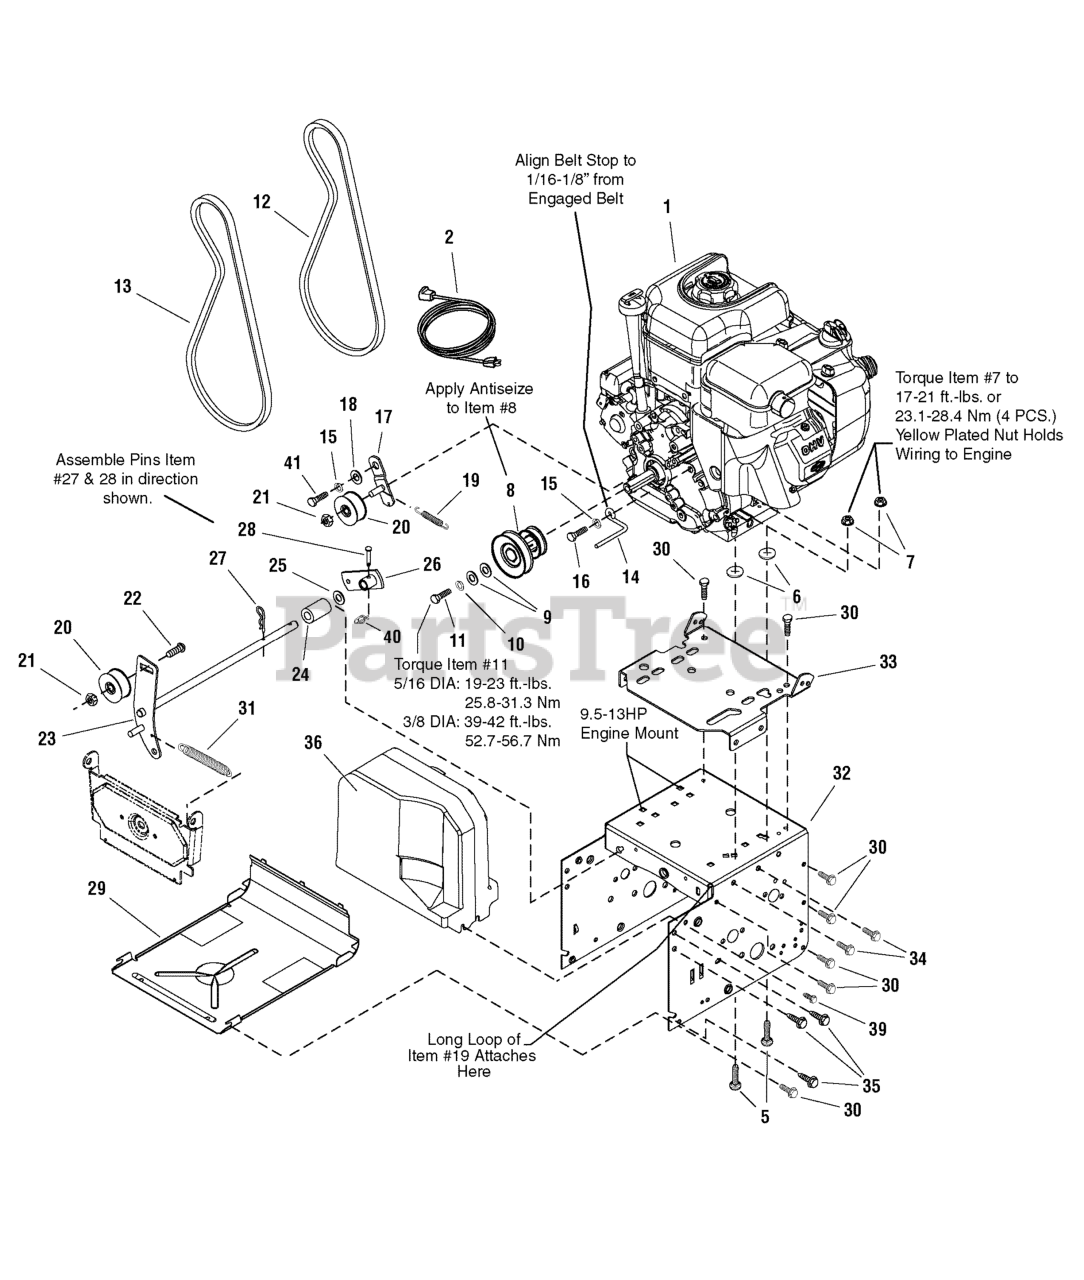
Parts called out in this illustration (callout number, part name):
1	ENGINE, B&S Powerbuilt *
2	CORD, Electric, 10FT. 110V
5	CARRIAGE BOLT
6	NUT, Speed
7	NUT, Hex-Flange 5/16-18
8	PULLEY, Engine
9	WASHER, 5/16
10	LOCKWASHER, 3/8
11	CAPSCREW, Hex Head, 5/16-24 x 1-1/4 G8
12	V-BELT, Drive
13	V-BELT, Auger
14	STOP, Belt
15	LOCKWASHER, Spring 5/16
16	CAPSCREW, Hex Head, 5/16-24 x 3/4 G5
17	IDLER BRACKET ASSEMBLY, Drive Belt
18	BUSHING, Idler Bracket
19	SPRING, Extension Idler
20	IDLER, Plastic Ball Bearing
21	NUT, Hex Jam, 3/8-16
22	CARRIAGE BOLT, 3/8-16 x 1-1/4
23	IDLER ASSEMBLY, Auger
24	SPACER, Auger Idler
25	WASHER, 1/2
26	BRACKET & HUB ASSEMBLY, Spring
27	PIN, Hair
28	PIN, Clevis
29	PANEL, Bottom
30	SCREW, Hex Washer Head Taptite, 1/4-20 x 5/8
31	SPRING, Extension Auger Idler
32	FRAME BOX
33	PLATE, Engine Mount
34	SCREW, Hex Washer Head Taptite, 5/16-18 x 1/2
35	SCREW, Hex Washer Head Taptite, 5/16-18 x 3/4
36	COVER, Belt
39	SCREW, Hex
40	PIN, Cotter, Self Lock, .25
41	SCREW, 5/16-24 x 1.00
